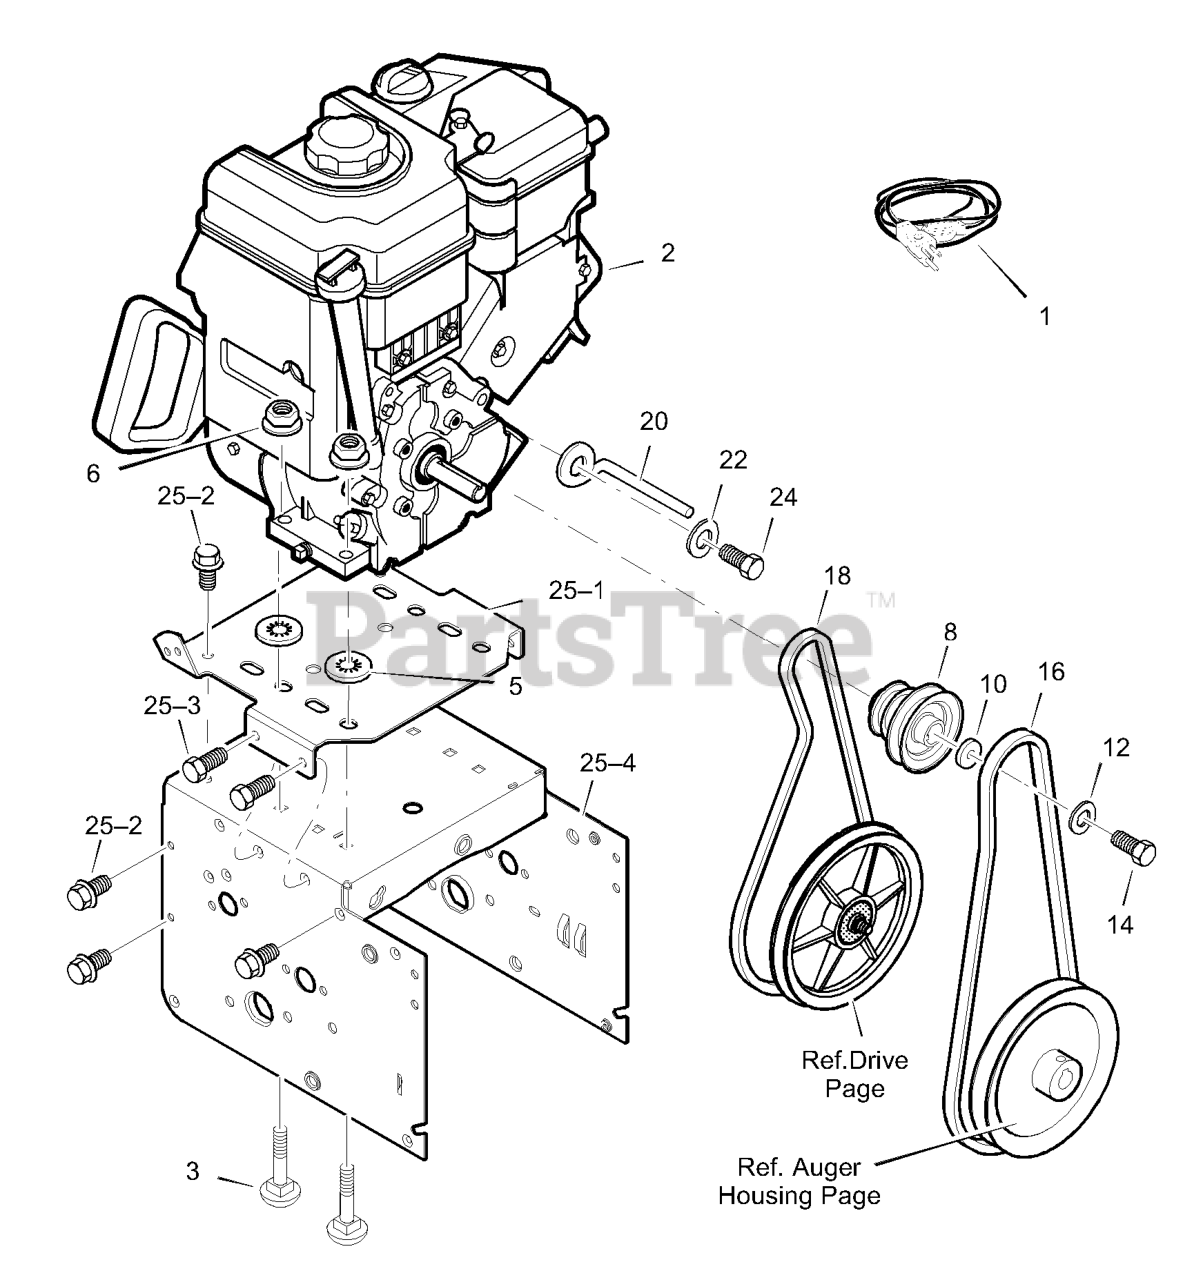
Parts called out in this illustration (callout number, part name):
1	CORD, STARTER
2	ENGINE
3	BOLT, CARRIAGE 5/16-18
5	RETAINER, PUSH
6	NUT, HEX 5/16-18
8	PULLEY, ENGINE
10	WASHER
12	WASHER .38ID
14	SCREW, 3/8-24 x 1.00
16	BELT, V 4L 38.1MF16" 5-10
18	BELT, V 3L 33.13LG
20	GUIDE, BELT
22	WASHER .31X.58X.08
24	SCREW, 5/16-24 x 0.75
25	FRAME ASSEMBLY
25-1	PLATE, ENGINE MOUNT
25-2	SCREW, TAP 1/4-20 X .63
25-3	SCREW, TAP 5/16-18 X .50
25-4	FRAME, MOTOR BOX
